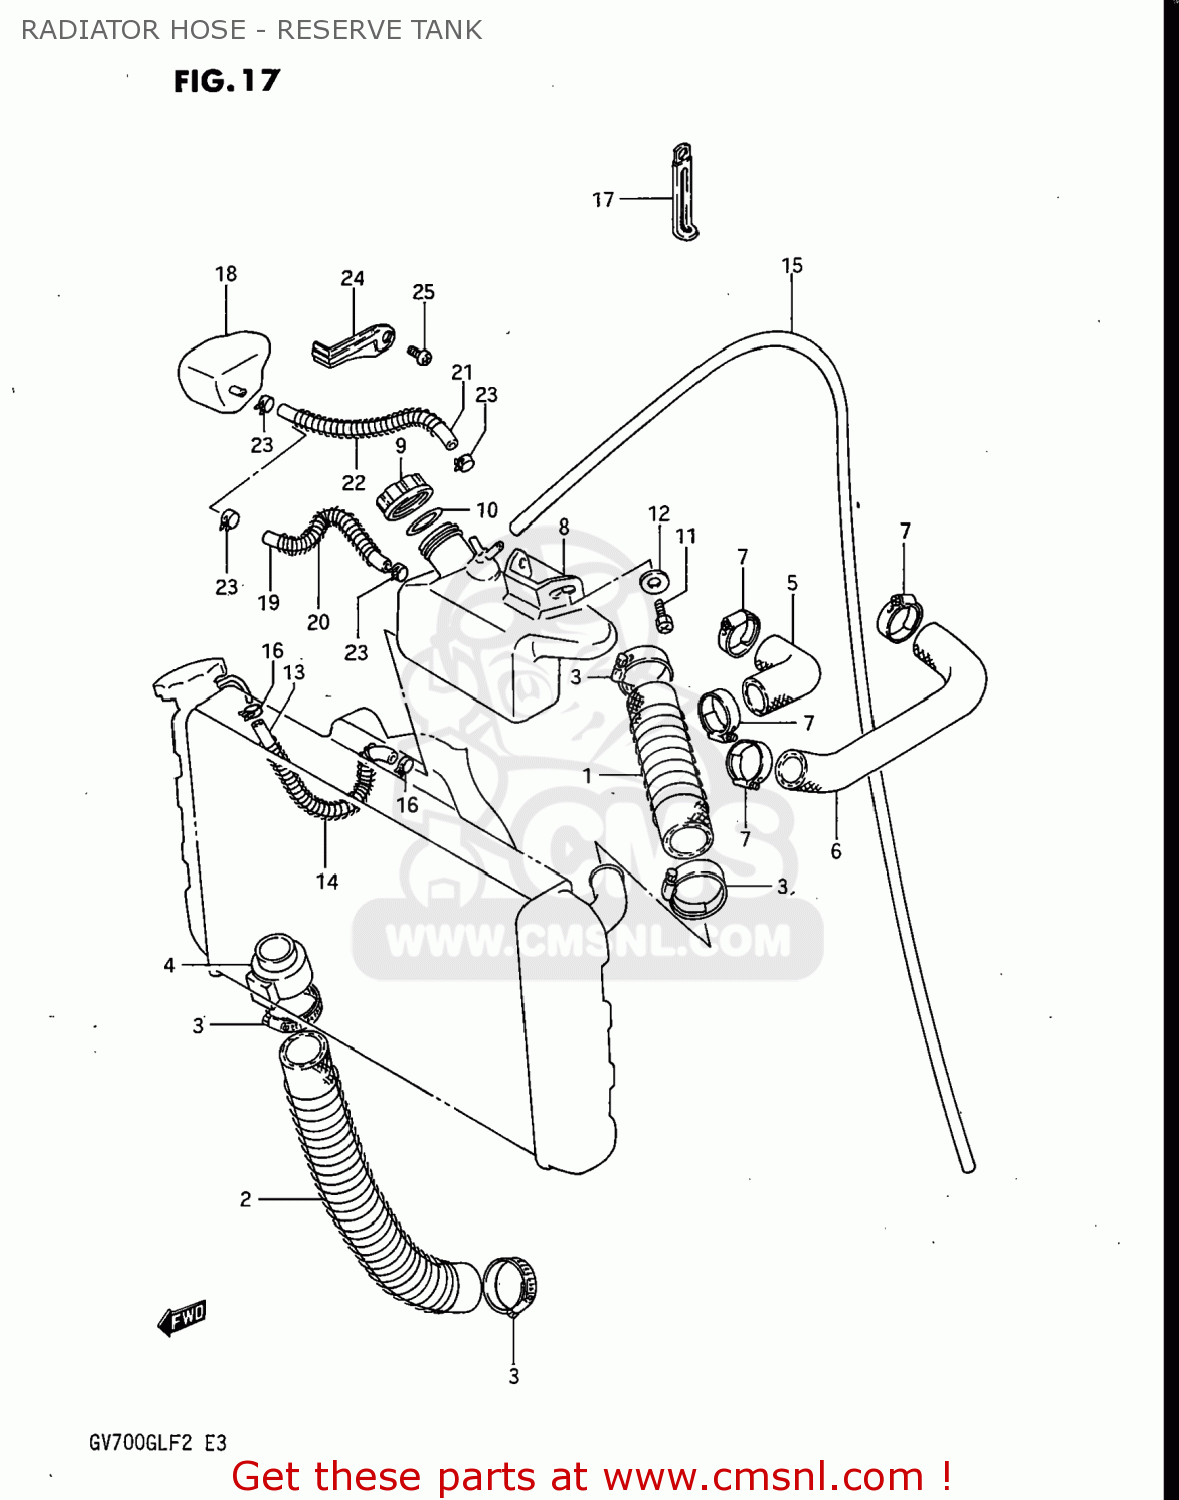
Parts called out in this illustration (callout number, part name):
1	HOSE,RADIATOR INLET
2	HOSE,RADIATOR OUTLET
3	CLAMP
4	HOSE,WATER
5	HOSE,THERMO IN FR
6	HOSE,THERMOMETER,IN,REAR
7	CLAMP
8	TANK,RESERVE
9	CAP,RESERVOIR TANK
10	GASKET,RESERVOIR TANK CAP (NAS)
11	SCREW
12	WASHER
13	HOSE,RESERVOIR TANK INLET
14	SPRING
15	HOSE
16	CLIP
17	CLAMP
19	HOSE,RESERVOIR INLET
20	SPRING
22	SPRING
23	CLIP
25	SCREW
